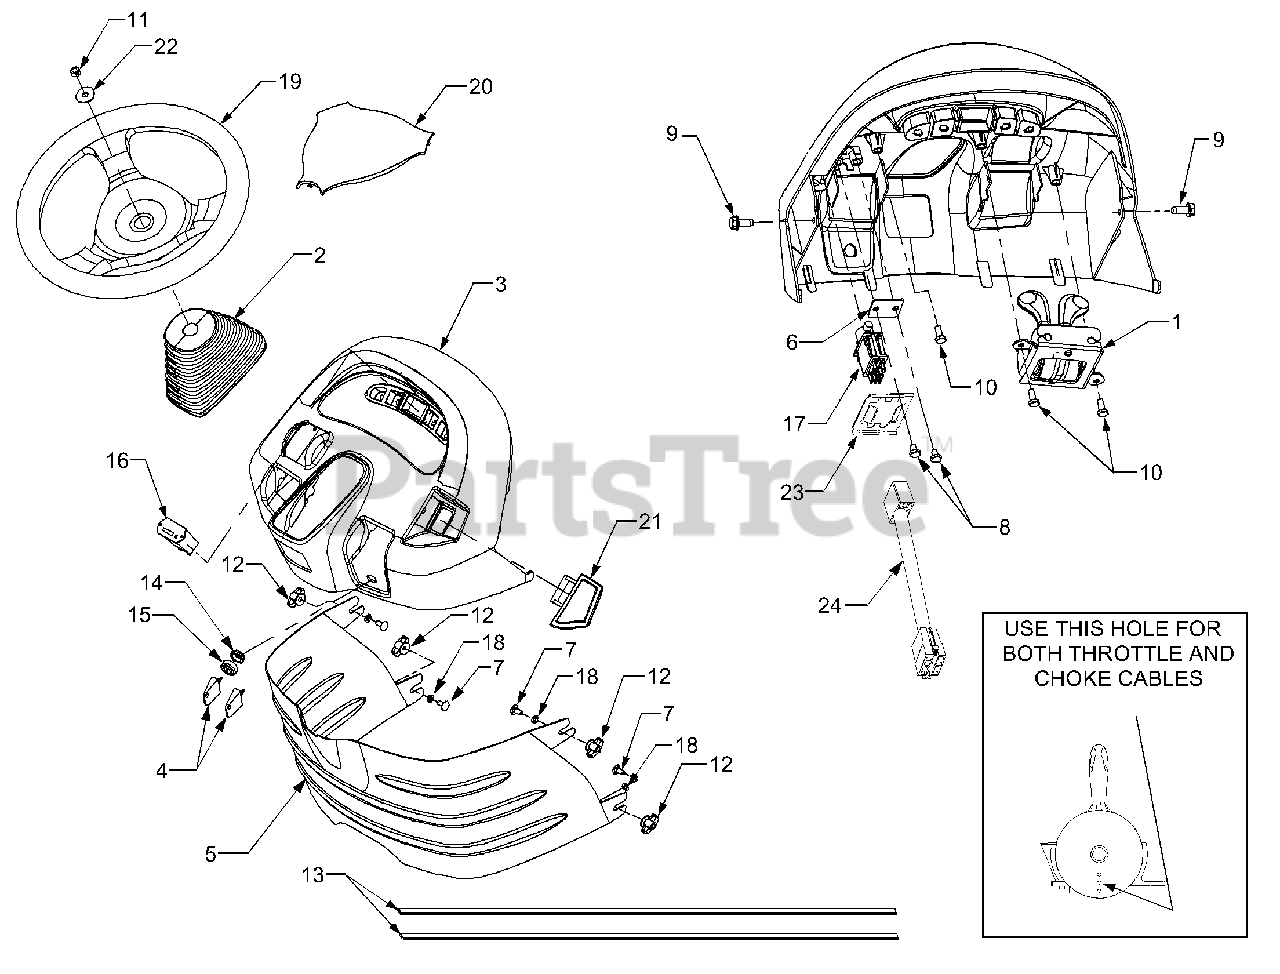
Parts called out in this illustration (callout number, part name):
1	Control Assembly, Throttle/Choke
2	Boot, Tilt Steer
3	Dash Panel
4	Key, Ignition (Set of 2)
7	Carriage Bolt, 1/4-20 x .62
8	Screw, Hex Cap 1/4-20 x .375 GR5
9	Screw, Hex Wash. Hd. Tapp 5/16-18 x .75
10	Screw, Hex Cap 1/4-20 x .50 GR5
11	Nut, Hex Lock, 5/16-24
12	Wing Nut, 1/4-20 w/Bell Washer
13	Seal, Screen
14	Nut, Ignition Switch, 5/8-32
15	Cap, Ignition Switch
16	Hour Meter
17	Switch, PTO
18	Nut, Push
19	Steering Wheel
20	Cover, Steering Wheel
21	Handle, PTO Switch
22	Washer, Flat, .34 x 1.5 x .10
23	Bracket, PTO Switch Retainer
24	Harness, PTO Adapter w/ Diode
